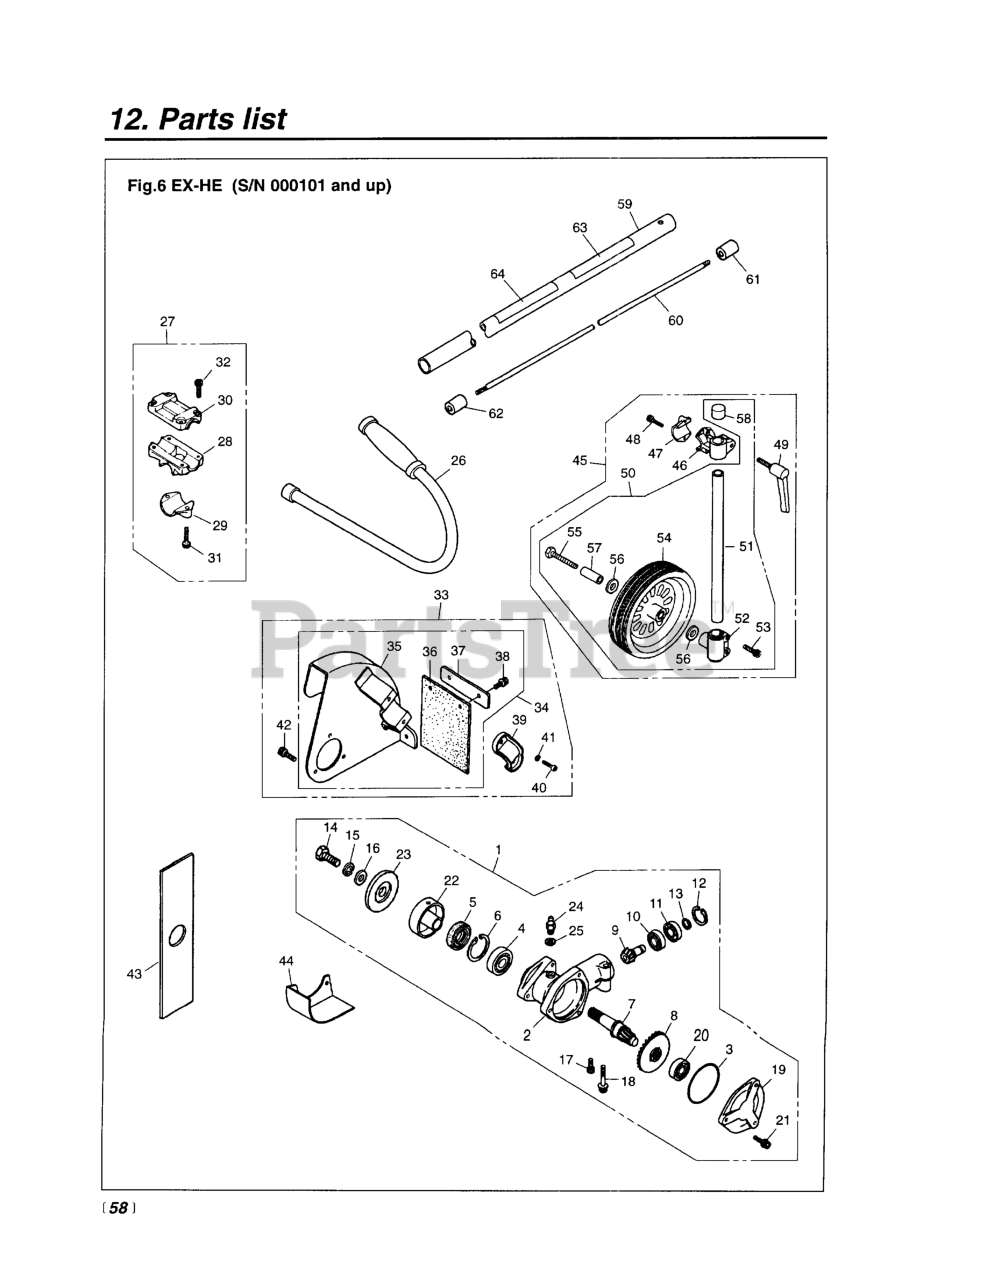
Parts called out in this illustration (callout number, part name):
3	O-RING
5	SEAL, OIL
6	RING, SNAP, M32 x 1.2
7	SHAFT, GEAR
8	GEAR
9	PINION
10	BEARING (RPLS T3403-13530)
11	BEARING (RPLS T3300-13531)
12	RING, SNAP, M24 x 1.2
13	RING, SNAP (RPLS T3300-13330)
14	BOLT, LH
15	WASHER (RPLS 3180-13270)
16	WASHER, M8 x 2.3 (RPLS -20823)
17	BOLT, M5 x 12
18	BOLT, M6 x 1.35
19	COVER
20	BEARING (RPLS T3403-13510)
21	BOLT
22	HOLDER (A)
23	HOLDER (B)
24	FITTING, GREASE
25	WASHER, M6 X .8
26	HANDLE, J
27	BRACKET ASSY (REPLACES -14100)
29	CAP, LOWER
30	CAP, UPPER (RPLS -14191)
31	BOLT, M5 X 22
32	BOLT, M5 X 25
34	COMP. GUARD
35	GUARD (RPLS 6367-24110)
36	PLATE (RUBBER)
37	PLATE (REPLACES -24130)
38	BOLT, M5 X 12
41	WASHER, M6 X 15
42	BOLT
43	BLADE, EDGER (RPLS 147315)
44	COVER (CAN USE 6367-96110)
45	WHEEL ASSY COMP (RPLS -25000)
46	BRACKET
47	CAP, LOWER
48	BOLT, M5 X 22
49	LEVER
50	WHEEL ASSY (RPLS -25100)
51	PIPE
53	BOLT, M6 X 25
54	WHEEL
55	BOLT (REPLACES -81060)
56	WASHER, M10 x 1.6
57	SPACER, PIPE
58	CAP
59	PIPE COMPLETE
60	SHAFT
61	JOINT, SHAFT (RPLS -12240)
62	SPACER
63	NAMEPLATE
64	PLATE, CAUTION
